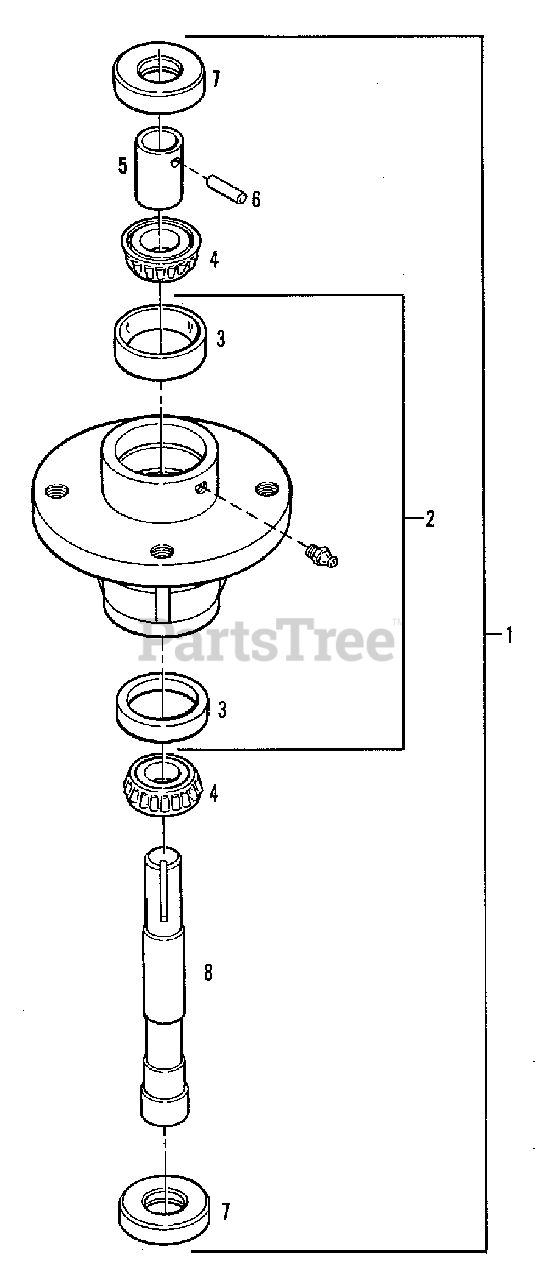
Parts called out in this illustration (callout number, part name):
1	SPINDLE & HUB ASSEMBLY, L.H. Rotation
2	HOUSING, Spindle
2	FITTING, Lube, 1/4 Straight
3	CUP, Bearing
4	CONE, Bearing
6	PIN, Self-Lock, 3/16" x 1-1/8
8	SHAFT, Spindle, L.H. Threads
